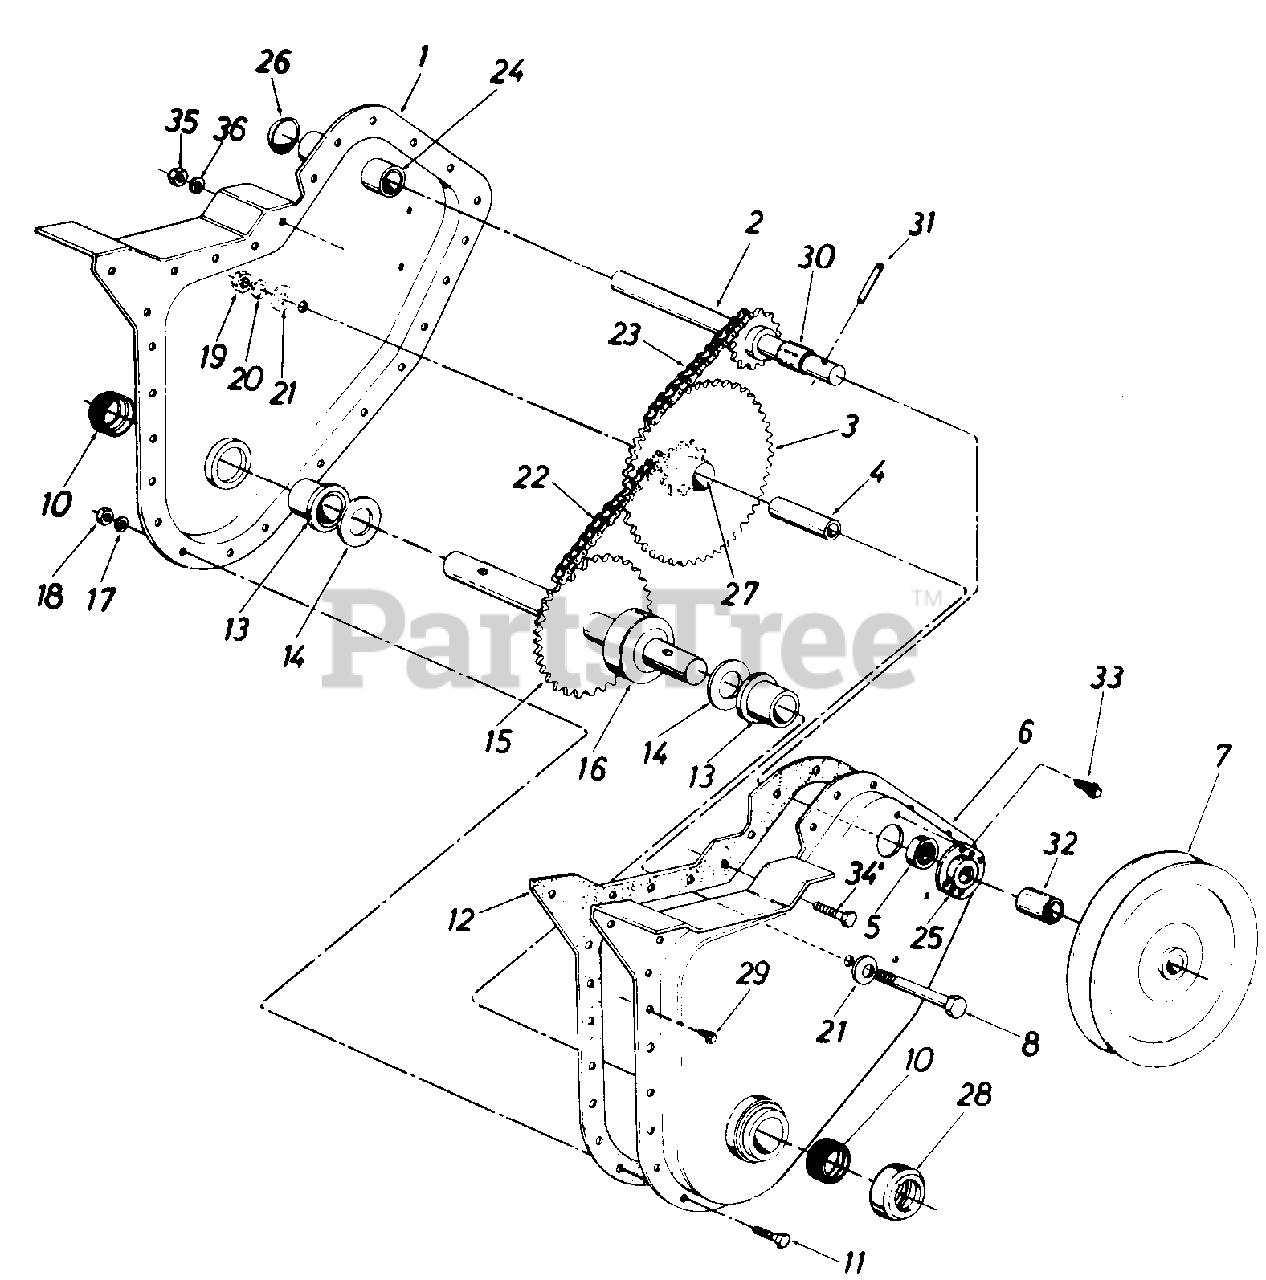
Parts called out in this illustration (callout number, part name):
1	Chain Case Ass'y.-R.H.
2	Input Shaft Ass'y.
3	Hub and Sprocket Ass'y.
4	Bearing Inner Race
5	Ball Bearing
6	Chain Case Ass'y.-L.H.
7	Pulley-Chain Case
8	Hex Bolt 3/8-24 x 2.5" Lg.
11	Hex Bolt 1/4-28 x .625" Lg.
12	Gasket
13	Flange Brg. .879" I.D.
14	Fl-Wash. .88" I.D. x 1.5"
15	Tine Shaft Ass'y.
16	Spacer 7/8" I.D. x 2" O.D. x.68" Lg.
17	L-Wash. 1/4" I.D.
18	Hex Nut 1/4-28 Thd.
19	Hex Ins. L-Nut 3/8-24 Thd.
20	L-Wash. 3/8" I.D.
21	Bell-Wash..406" I.D.
22	Chain #420 1/2" Pitch x 37 Links
23	Chain #35 .375" Pitch x 49 Links
24	Bearing .62" I.D. x.813"
25	Bearing Housing
26	Expansion Plug 13/16" Dia.
27	Bearing
28	Dust Cap
29	Hex Wash. Hd. Self-Tap Scr. 1/4-20 x .50" Lg.
30	Spacer .63" I.D. x .77" O.D. x .38" Lg.
31	Spring Pin Spiral 1/4" Dia. x 1 1/2" Lg.
32	Spacer .647 x 1 25"
33	Hex Wash. Hd. Self-Tap Scr. 1/4-20 x .38" Lg.
34	Hex Bolt 5/16-18 x .75" Lg.
35	Hex Nut 5/16-18 Thd.
36	L-Wash. 5/16" I.D.
